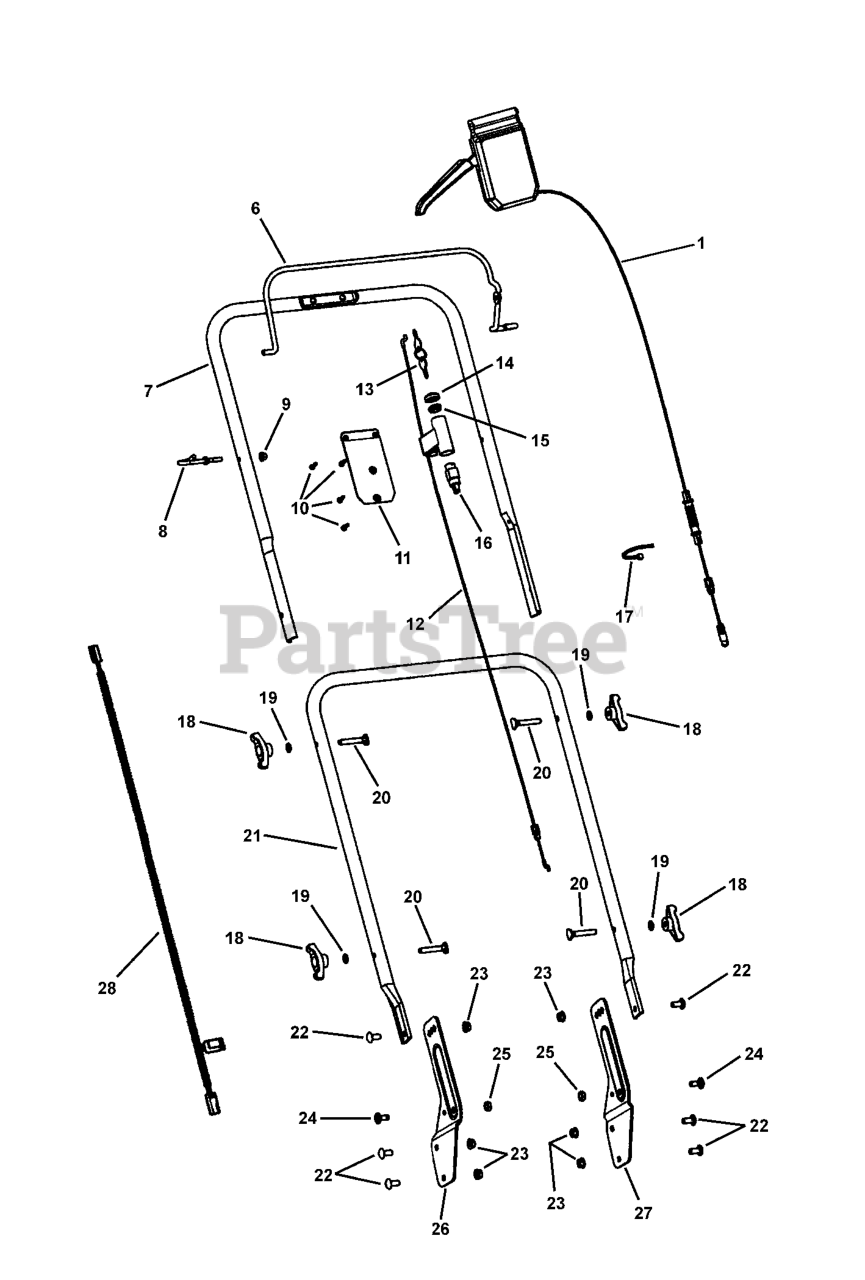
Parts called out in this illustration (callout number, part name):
1	CONTROL HEAD ASSEMBLY, SINGLE SPEED, BRUTE
6	BAIL, OPC PROPELLED BRUTE
7	HANDLE, UPPER, BRUTE, PROPELLED
8	GUIDE, ROPE (1/4-20 thread)
9	NUT, HEX FLANGE, 1/4-20, ESNA, YZ
10	#8-16 TORXPLUS RECESSED PAN HEAD, TWIN HELIX
11	CONTROL PANEL PLATE
12	CABLE, BAIL, 21" WBM, BRUTE, ES
13	IGNITION KEY PAIR
14	CAP, E-START
15	NUT, 5/8"-32 E-START
16	SWITCH, E/S (START/RUN)
17	WIRE TIE, 11 INCH STD BLK NYLON
18	KNOB, 5/16-18 WING (BLACK)
19	WASHER, 5/16
20	CHSNB, 5/16-18 X 2 GR2
21	HANDLE, LOWER 21" RD, JD
22	BOLT, 5/16-18 X 3/4 GR5 YZ
23	FLANGE NUT, 5/16-18 YZ
24	BOLT, 5/16-18 X 3/4 GR5 BZ
25	NUT, Hex Jam, 5/16-18
26	LOWER HANDLE BRACKET, LH, JD 21" WBM, RD
27	LOWER HANDLE BRACKET, RH, JD 21" WBM, RD
28	WIRE HARNESS, SNAPPER, RD 21"
